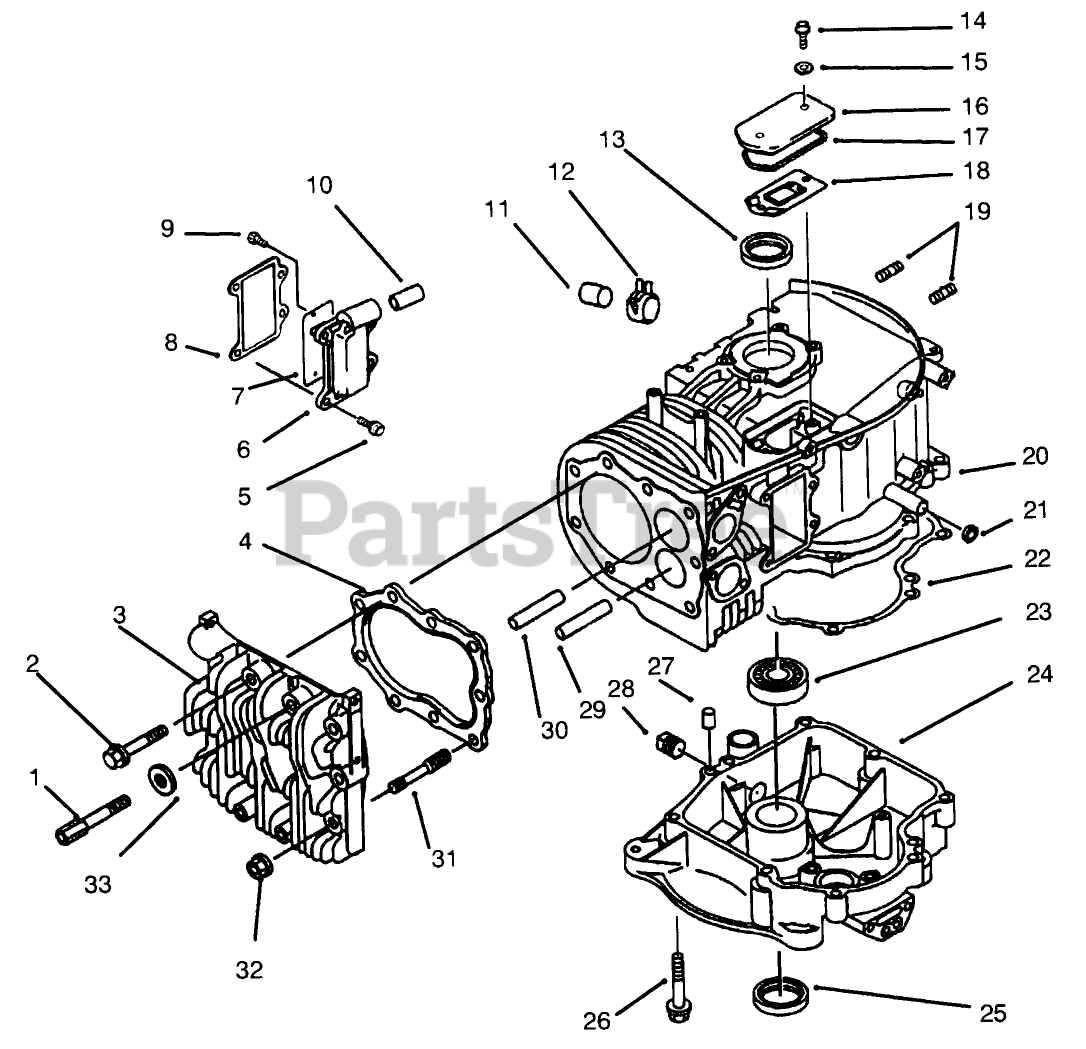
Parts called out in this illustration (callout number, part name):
1	Bolt
2	Bolt
3	Head-Cylinder
4	Gasket-Head
5	Bolt-Flanged (6X16)
6	Cover-Valve Chamber
7	Cover
8	Gasket
9	Screw
10	Tube
11	Plug
12	Clamp
13	Oil Seal
14	Bolt
15	Gasket
16	Cover
17	Gasket
18	Breather
19	Stud
20	Crankcase-Complete (Incl. Ref. #29, 30)
21	SEAL-OIL (VC6X10X2.6)
22	Gasket-Crankcase
23	Ball Bearing
24	Cover-Crankcase
25	Seal-Oil
26	Bolt-Flanged (8X45)
27	Pin
28	Plug
29	Guide-Exhaust Valve
30	Guide-Intake Valve
31	Stud
32	Nut
33	Washer
